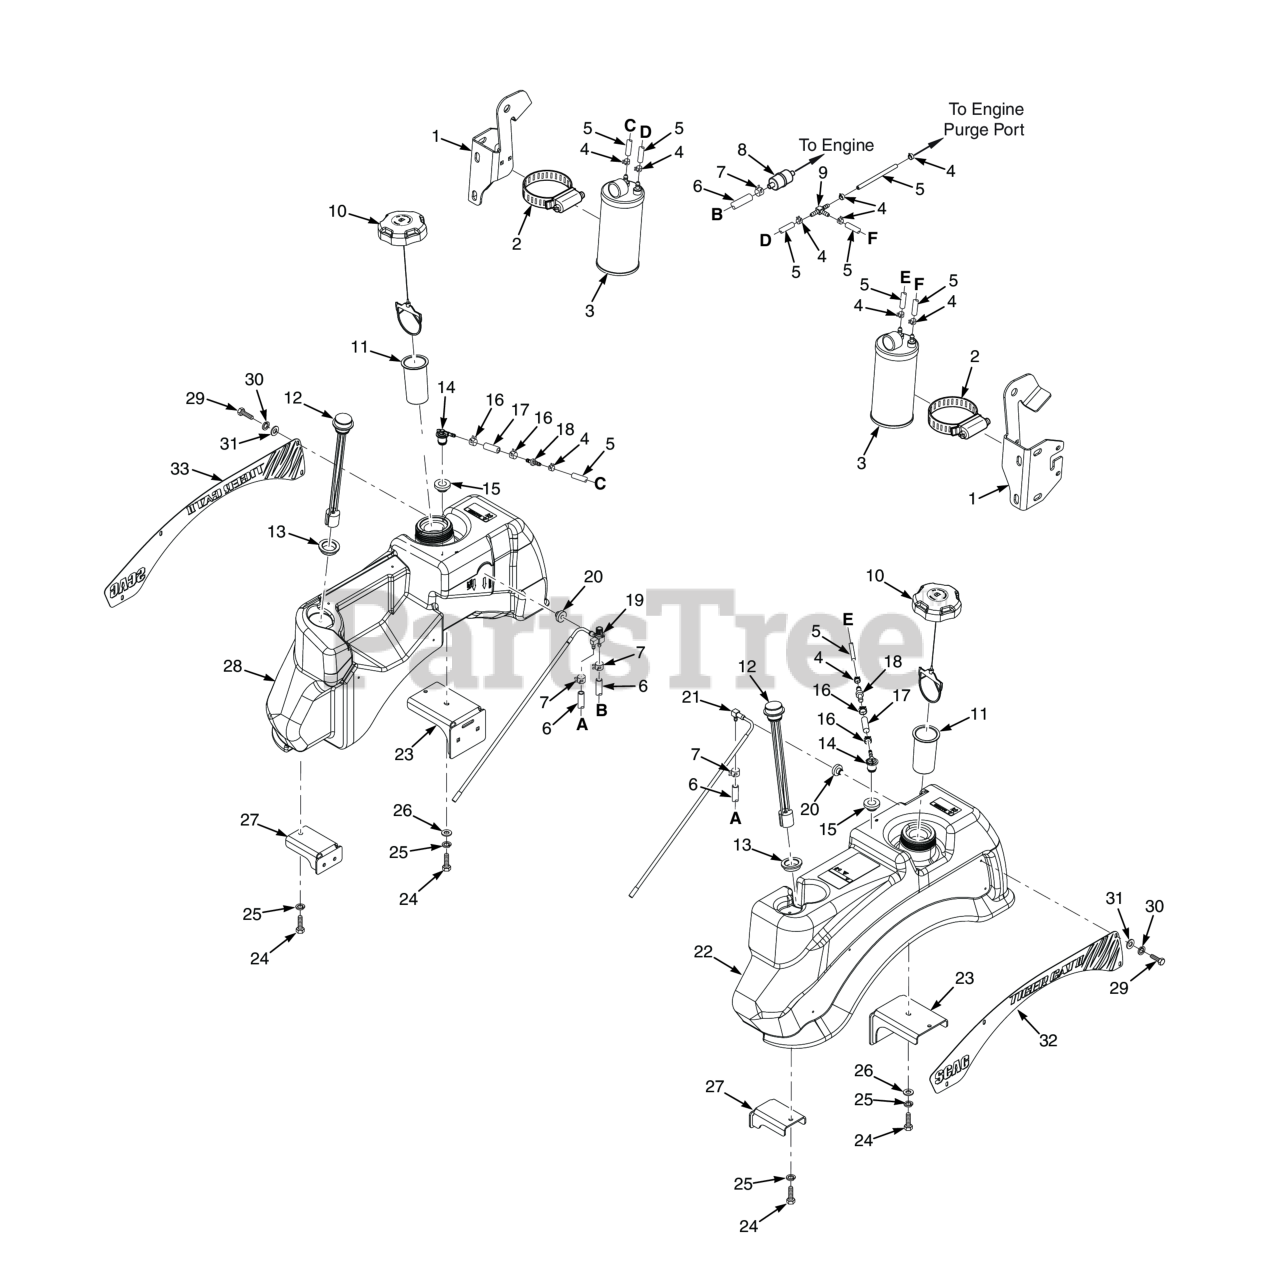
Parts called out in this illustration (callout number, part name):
1	ROPS Mount, LH, 22 & 23FX / 23CV / 24FT / 26FT-EFI / 25CV-EFI
2	Clamp, 3-1/2" Max. Dia.
3	Carbon Canister - SVR-36A / SVR-48V
4	Clamp, Vapor Recovery Hose 3/16"
5	Hose, Vapor Recovery 3/16" (order by inch)
6	Fuel Hose, 1/4" I.D. Non-Perm (791DFI Fuel Return) - Order by Inch
7	Clamp, Fuel Hose 1/4" Hose I.D.
8	Fuel Filter
9	Tee, 3/16 x 3/16 x 3/16 Union, Hose Barb
10	Fuel Cap w/ Tether (E.P.A.)
11	Tube, Fuel Tank Insert - 4"
12	Fuel Gauge Assembly
13	Grommet, Fuel Gauge
14	Remote Vent, No Valve
15	Grommet, Viton,
16	CLAMP, FUEL HOSE(KAWASAKI ONLY)
17	Hose, 1/4" Vapor Recovery (order by inch)
18	Mender, 1/4 x 3/16 w/0.02 Hole
19	Fuel Tube Assembly, Includes Valve
20	Bushing, 0.56" Dia. Viton
21	Fuel Tube Assembly, LH
22	Fuel Tank Assembly, LH (incl. # 12, 14, 15, 20, 21, 29, 30, 31, 32)
23	Mounting Bracket, Fuel Tank Rear
24	BOLT, SERRATED FLANGE HEX HEAD 5/16-18 X 3/4"
25	Lockwasher, 5/16 (.317 x .586 x .078) Helical Spring
26	Flatwasher, 5/16-.375 x .875 x .083 (35BV & 37BV-EFI)
27	Mounting Bracket, Fuel Tank Front
28	Fuel Tank Assembly, RH (incl. #12, 14, 15, 19, 20, 29, 30, 31, 33)
29	Bolt, Hex Head 1/4-20 x .5" Battery, (Not Available Through Scag)
30	Lockwasher, 1/4� Spring
31	Flatwasher, 1/4 (.258 x .500 x .0598)
32	Logo, Scag Tiger Cat II (RH)
33	Logo, Scag Tiger Cat II (LH)
